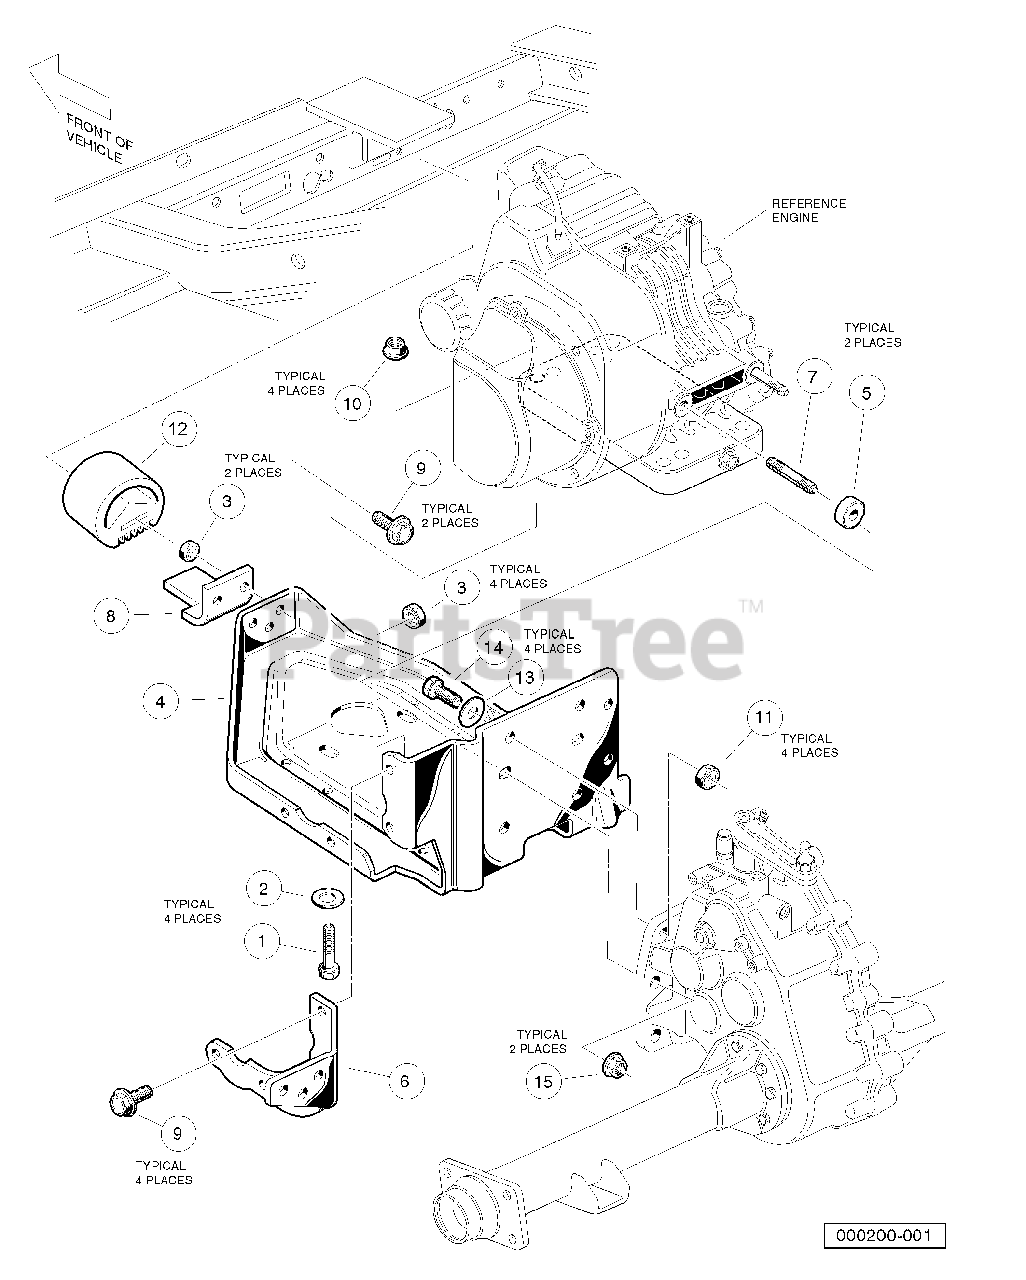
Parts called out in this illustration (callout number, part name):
1	Bolt, Hex-Head, 5/16-18 X 1.50
2	Washer, 5/16 Extra Thick Flat
3	Nut, 5/16-24 Hex Head Cone
4	Plate, Engine Mounting
5	Spacer, Powdered Metal
6	Stiffener
7	Stud, M8-1.25 X 60mm Two-Ended
8	Snubber Bracket
9	Screw, 5/16-24 X 0.875 Grade-8
10	Locknut, 5/16-18 Hex Flange
11	Locknut, 3/8-16 Flanged Dimple
12	Inner Frame Snubber
13	Washer, 3/8 Type A Flat
14	Screw, Cap-hex Hd 3/8-16x1.25
15	Nut Flg, M8 X 1.25 Serrated
